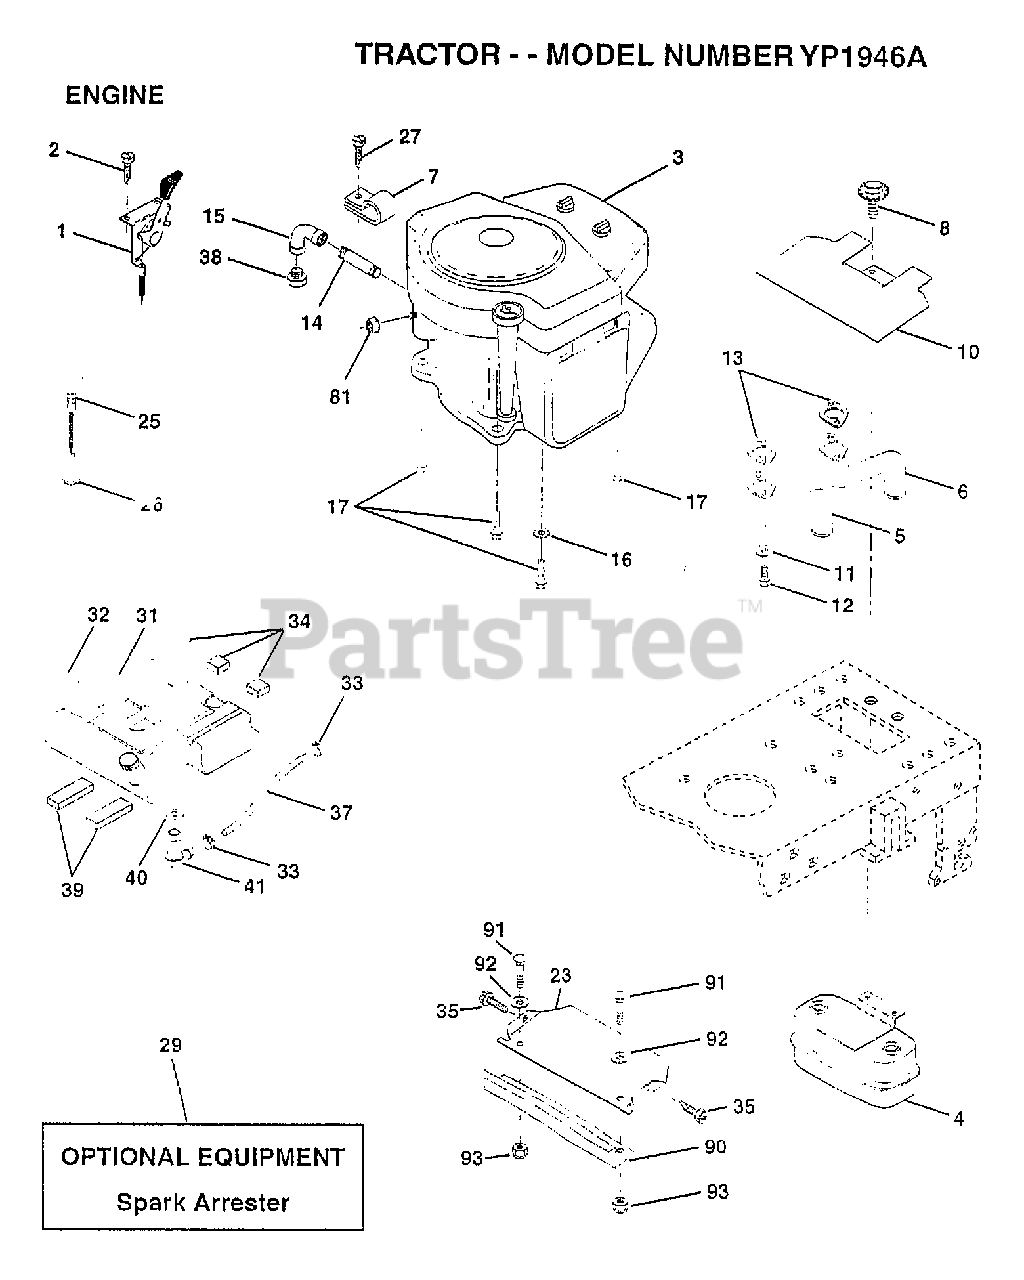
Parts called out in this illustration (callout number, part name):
1	CONTROL THRT 35.5
2	SCREW LT
4	MUFFLER.TW.LOTONE
5	EXHAUST.B&S.18.LH
6	EXHAUST.B&S.18.RH
7	CLAMP.TUBE.DBL.EN
8	BOLT.5/16-18.UNC
10	SHIELD.HEAT.
14	PIPE NIPPLE LT
15	ELBOW
16	LOCKWASHER
17	SCREW LT
23	SHIELD-HEAT
25	CONTROL.CHOKE.37
26	"NUT,KEPS 3/8-24IM"
27	"SCREW-TT,10-32 FL"
31	TANK FUEL REAR
32	CAP ASM FUEL
33	HOSE CLAMP
34	PAD-SPACER LT
35	SCREW
37	FUEL LINE T
39	PAD IDLER TI
40	BUSHING OUTLET T
41	STEM.TANK.FUEL
81	NUT
90	GUARD-DEBRIS
91	CONFLICT W/PART #
92	WASHER
